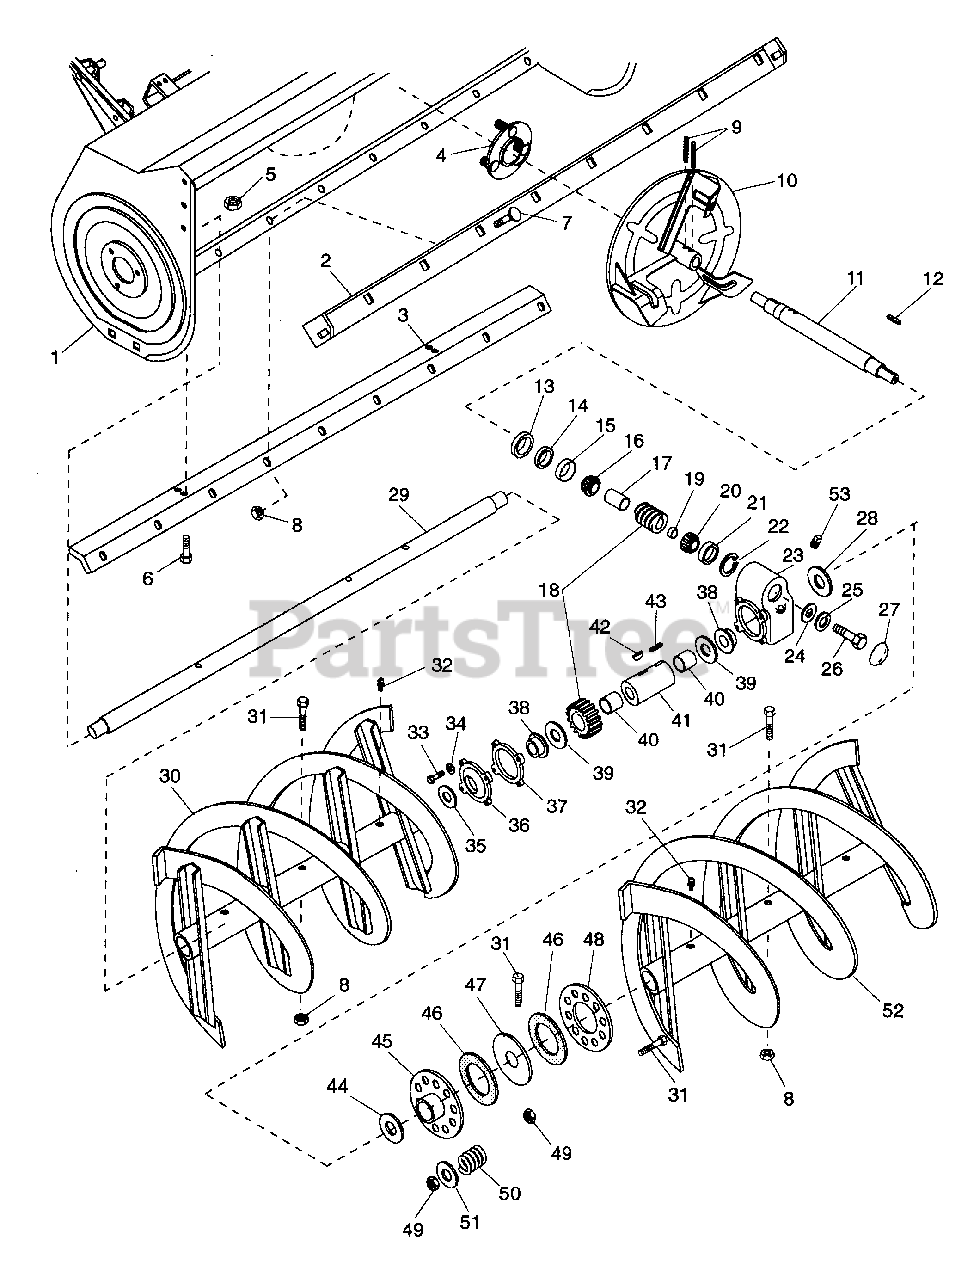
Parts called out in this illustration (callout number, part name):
1	48 AUGER/16 IMPELLER HOUSING
2	SCRAPER BLADE
3	SCRAPER BLADE BRACE (A)
4	BEARING FLANGE
5	NUT-LK TOP .375-16 GR C YWZC
6	BLT-HEX .38-16X.75 PL GR5
7	BLT-RDHDSQNK .31-18X.75 SHT PL
8	NUT-LK .312-18 GR A PL
9	PIN-ROLL .313X1.75
10	FAN 16 INCH
11	WORM SHAFT
12	KEY-SQ .188X1.0X.188 SAE 8630
13	ADJUSTMENT PLUG
14	SEAL 1.125X1.375X.125
15	BRG-CUP1.980X.420
16	BRG-CONE 1.0X.58
17	BEARING SPACER 1.032X1.25X1.78
18	WORM & GEAR SERVICE ASSEMBLY
19	BSHG, SPCR .755X1.12X.50 PM
20	BRG-CONE .750X.61
21	BRG-CUP 1.781X.475
22	RG-RTNG-INT 1.781X.062
23	GEAR CASE - CAST IRON
24	WSHR-FL-STL .328X1.0X.094 PL
25	WSHR-LK .312X.097 PL HVY
26	BLT-HEX .31-18X.75 PL GR2
27	DUST CAP
28	SEAL 1.625X2.125X.250
29	48 INCH RAKE SHAFT
30	RAKE, RIGHT-48(1.12ID X 15.75)
31	BLT-HEX .31-18X2.00 PL GR5
32	FTG-LUBE .25-28X.256 YWZC
33	BLT-HEX .25-20X.75 PL GR2
34	WSHR-LK-EXT. 250 ID
35	SEAL 1.625X2.125X.250
36	GEAR CASE COVER
38	BSHG-FLG .683X1.87X1.68X2.250
39	WSHR-FL-STL 1.625X2.500X.012
40	BSHG-SLV 1.125X1.250X1.000
41	GEAR CASE SHAFT
42	KEY-FTHR .25X.875X.25 SAE 8630
43	KEY-SQ .25X.625X.375
44	WSHR-FL-NYL 1.625X2.500X.060
46	FRICTION DISC
47	DRIVEN PLATE
48	PRESSURE PLATE
49	NUT-LK-TOP .312-18 GR C PL
50	SG-COMP .156X.665X.75
51	WSHR-FL-STL .323X.625X.062 PL
52	RAKE, LEFT-48"(1.12ID X 15.75)
53	PIPE PLUG
